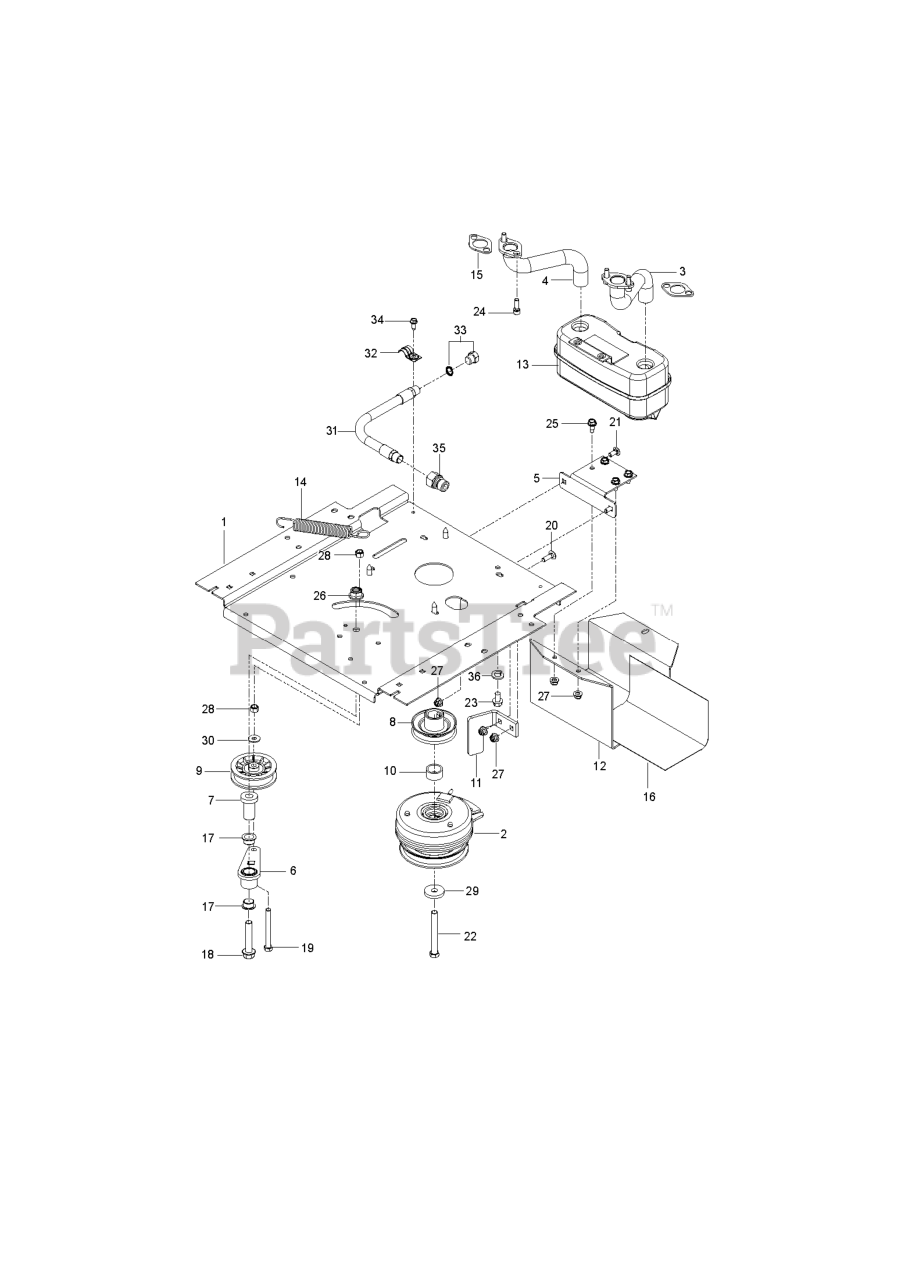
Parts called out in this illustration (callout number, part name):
1	PLATE.ENGINE.PNT.23"FRAME.EDIP
2	CLUTCH.105.FT-LBS
3	PIPE.EXHAUST.LH.CV18/20
3	EXHAUST.TUBE.LH.BS/TWIN
4	PIPE.EXHAUST.RH.CV18/20
4	TUBE.EXHAUST.RH.FR961/FR730
4	EXHAUST.TUBE.RH.B&S.TWIN.INTEK
5	BRACKET MUFFLER MS431BLK
6	ARM IDLER
7	SPINDLE.IDLER
8	PULLEY.ENGINE
9	PULLEY, IDLER RAKE & ZTR
10	T & B SPACER
11	STOP, CLUTCH, BLACK
12	GUARD.MUFFLER.WO.TOW.HITCHX431
13	MUFFLER ASM TWIN
14	SPRING, DECK DRIVE
15	GASKET.EXHAUST.KOHL.CV18-CV26
15	GASKET.MUFFLER
15	GASKET
16	HEAT SHIELD
17	CLUTCH BOLT7/16-20X3.5 GR524HR
17	BEARING.FLANGED.PLASTIC.3/4ID
18	BOLT.FLANGE.1/2-13 X 2.75.GRD5
19	HCS 3/8-16X3-1/2 TAPBLT GR5 ZD
20	BOLT
20	RHSNB 5/16C X 1
21	BOLT 5/16C X 3/4" CARRIAGE
21	RP BOLT 5/16-18 X3/4 ZN/YEL GR
22	CLUTCH BOLT7/16-20X3.5 GR524HR
23	BOLT
23	SCREW 3/8-16X1
24	SCREW.SOCKET HD.5/16-1
24	SCREW.SOCKET.HEAD.5/16-18
25	BOLT
25	SCREW.THDROL.5/16-18X3/4.TTY
25	SCREW 3/8-16X1
26	NUT, 1/2-13 HEX FLG NYLOC ZD
27	5/16-18 NYLOC FLANGE NUT
28	NUT 3/8-16 NYLOC
30	WASHER 5/16 FLAT
31	HOSE.ASSEMBLY.OIL.DRAIN
32	CLAMP
33	PLUG OIL DRAIN
34	SCR 1/4-20X5/8 HEX SELF TAP ZD
35	ADAPTER, OIL DRAIN
36	SLW 3/8 STD
